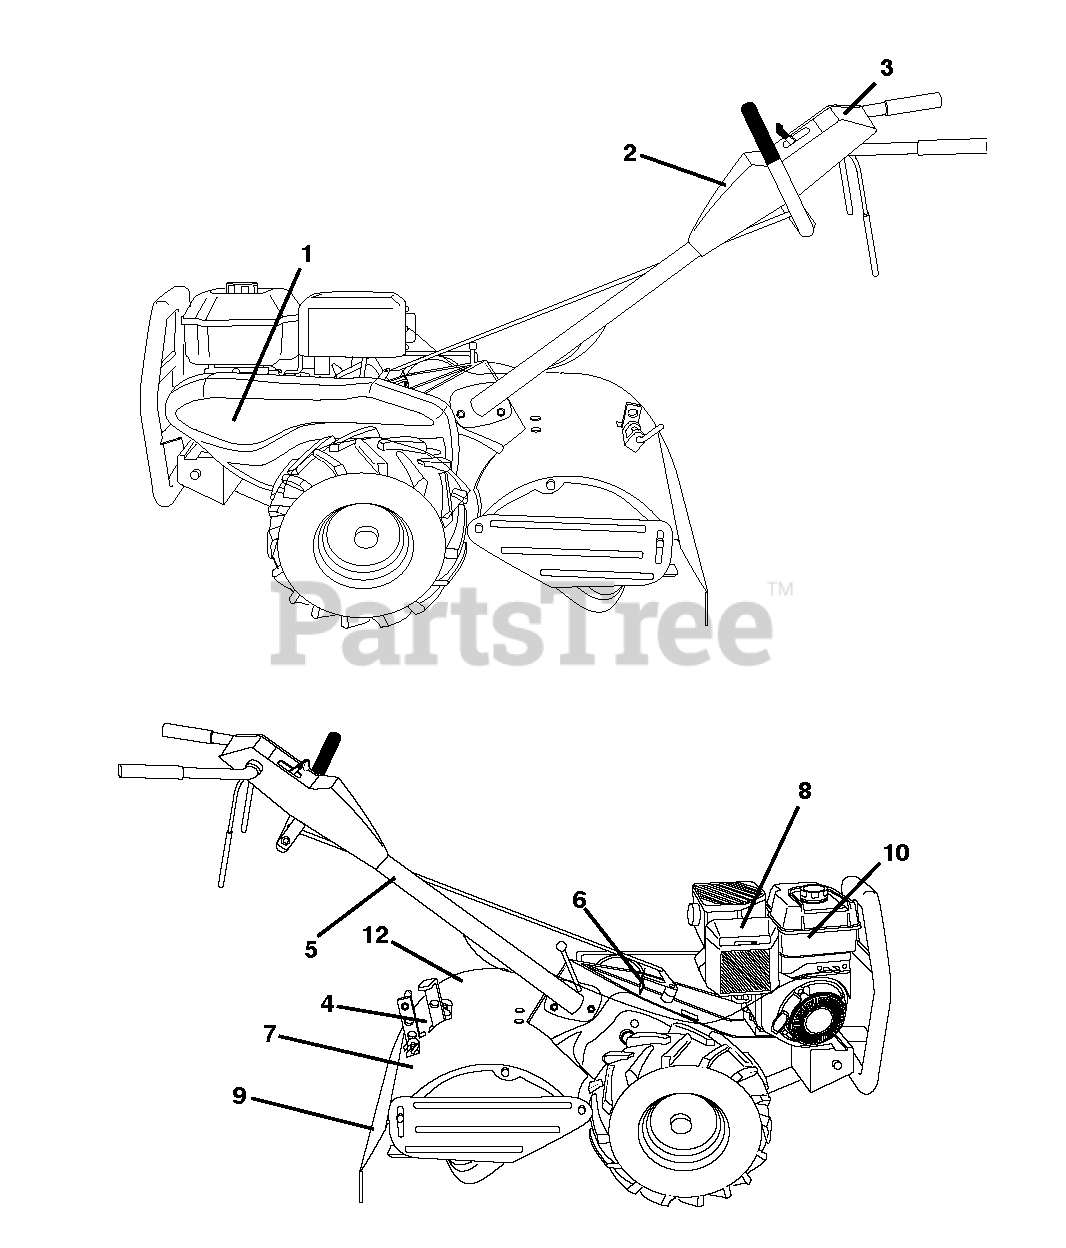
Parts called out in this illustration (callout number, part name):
1	RP.DECAL.BADGE.170MM.TEXTLOGO
2	DECAL.CNSL.DRT900/HUSQVARNA
4	DECAL.SHIELD.TN.DRT17.HUSQ
5	DECAL TI (2 2)
6	DECAL.SHIFT.INDICATOR.DRT
7	DECAL.REVERSE.HUSQ.TILLER
8	DECAL.B&S.900.A/S.C (279005)
9	DECAL.DRT.WARN.ENG/F
10	DECAL.B&S.900.TANK.REF.276991
12	DECAL.FOWARD.HUSQ.TILLER
